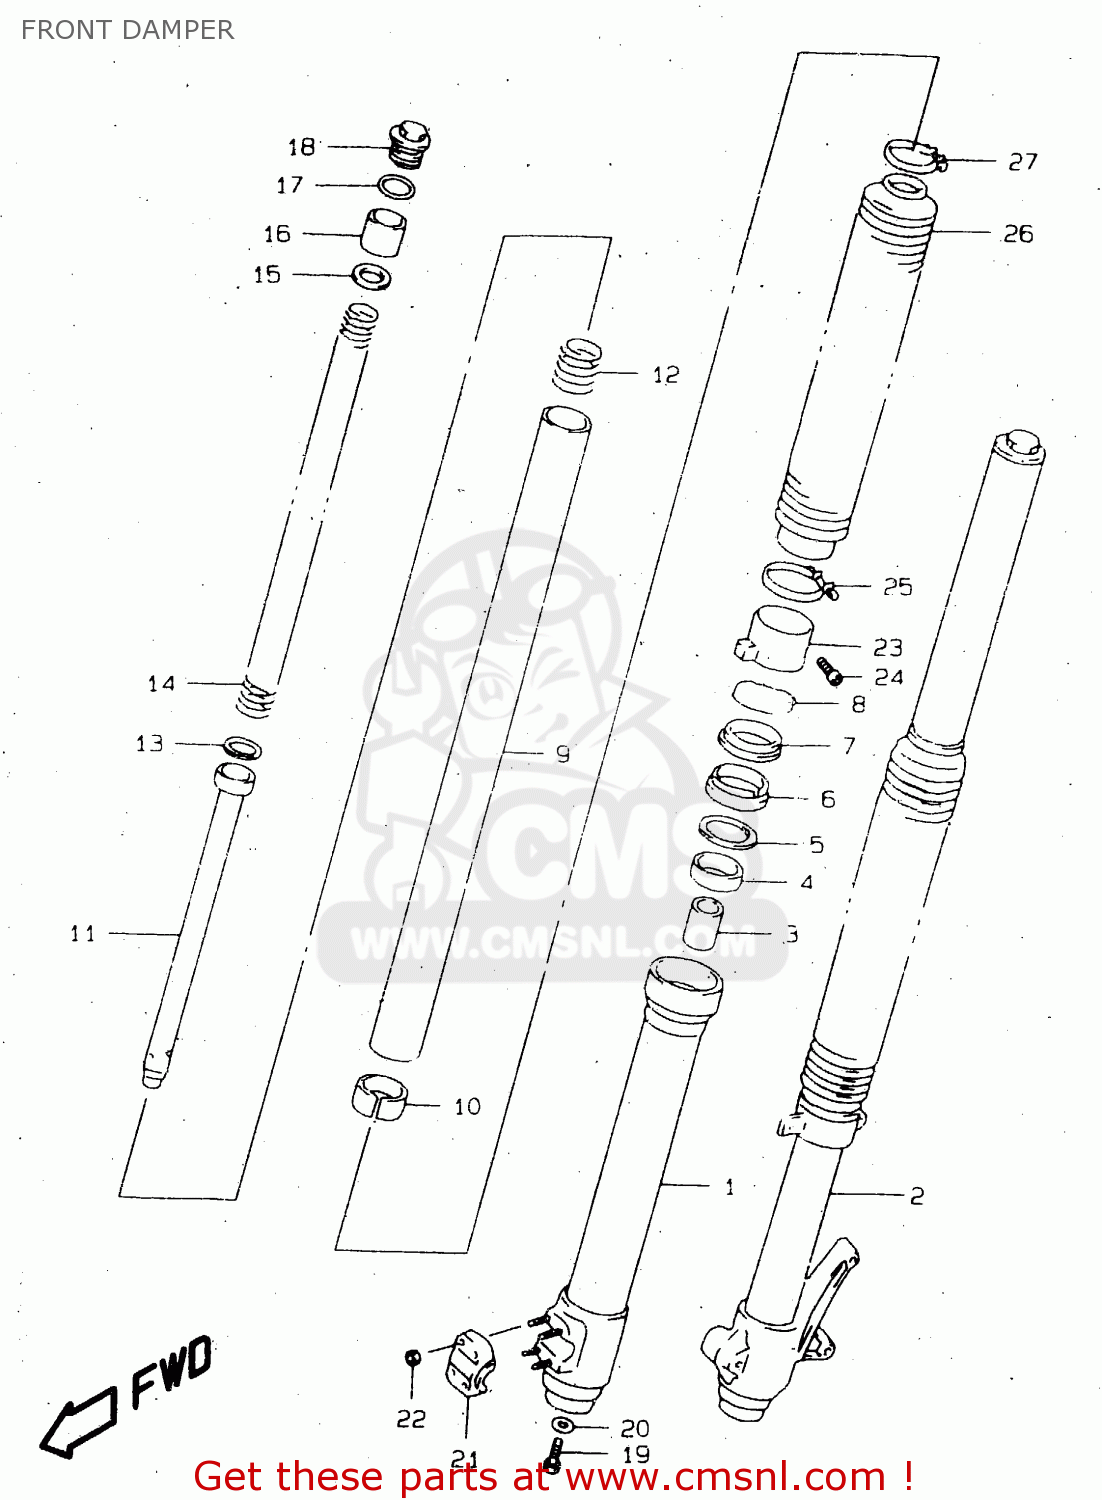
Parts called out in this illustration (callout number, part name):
1	TUBE,OUTER,R
2	TUBE,OUTER,L
3	PIECE,OIL LOCK
4	METAL,SLIDE
5	WASHER
6	SEAL,OIL
7	SEAL,DUST
8	RING,STOPPER
9	TUBE,INNER
10	PISTON
11	CYLINDER
12	SPRING,REBOUND
13	RING,PISTON
14	SPRING
15	WASHER
16	SPACER
17	O RING
18	CAP,FORK
19	BOLT,FORK CYLINDER(10X25)
20	GASKET (NAS)
21	HOLDER,AXLE,R
22	NUT
23	GUIDE,BOOT
24	BOLT
25	BAND,BOOT LWR
26	BOOT(GRAY)
27	BAND,BOOT
